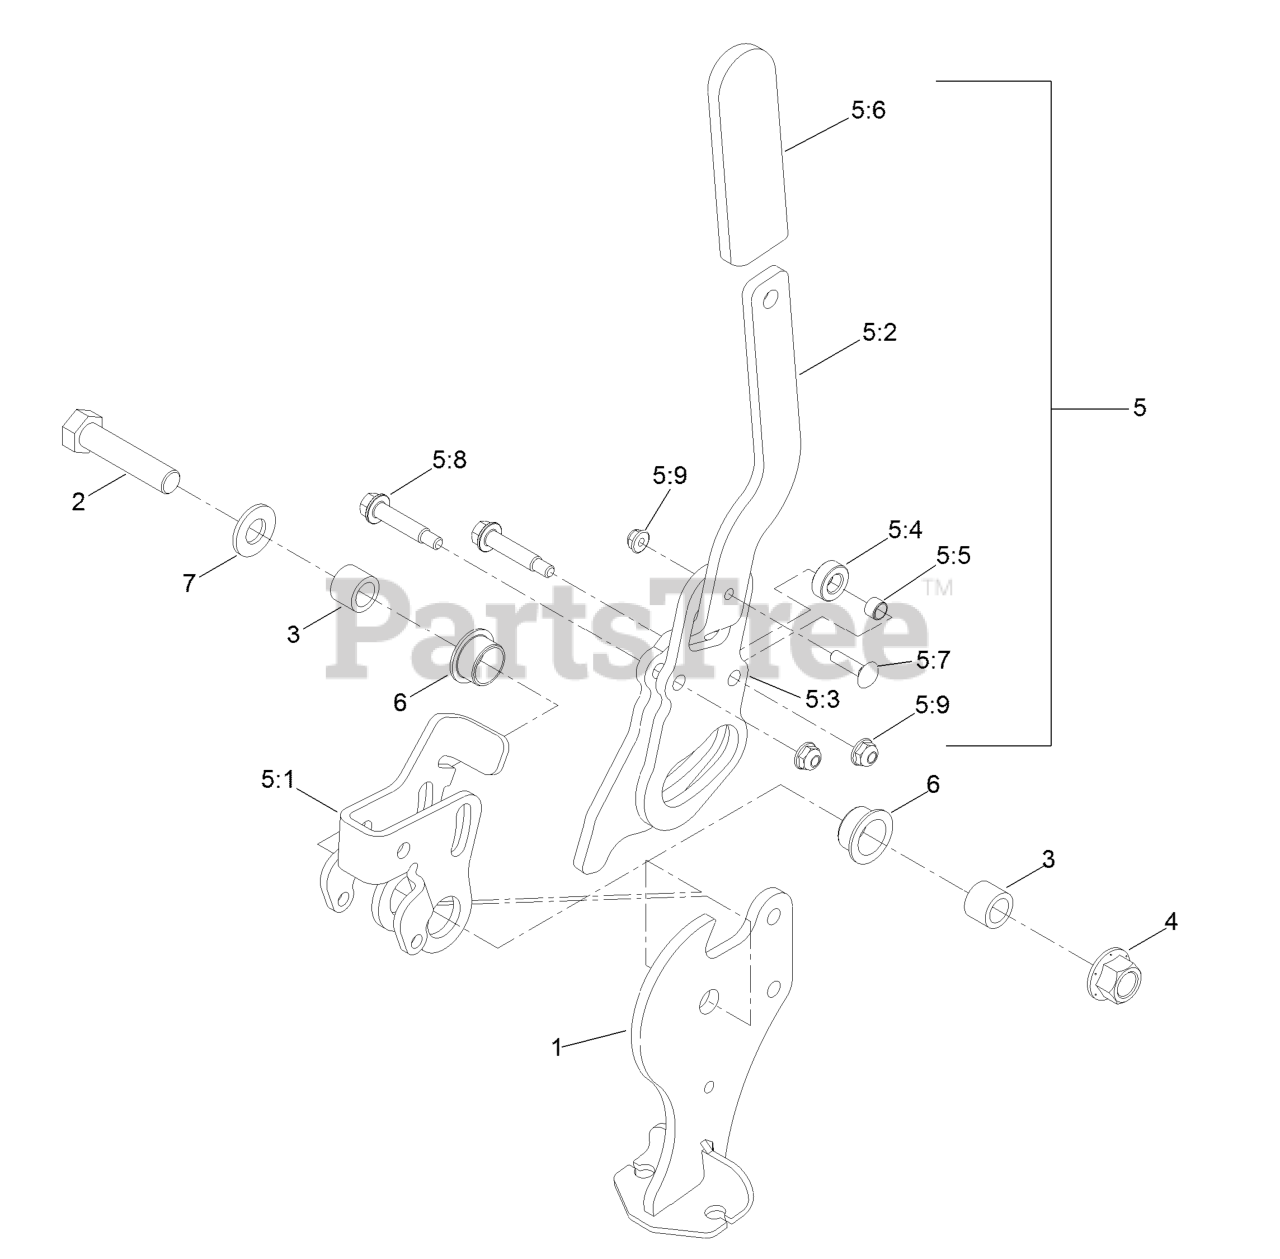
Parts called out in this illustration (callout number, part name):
1	PIVOT-BRAKE
2	SCREW-HH
4	Nut-Lock 1/2-13
5	HANDLE ASM
5:1	BELLCRANK-BRAKE
5:2	HANDLE-BRAKE
5:3	PLATE-HANDLE
5:4	ROLLER-BRAKE
5:5	BEARING-SLEEVE
5:6	GRIP-LEVER
5:7	SCREW-CARR
5:8	SCREW-SHOULDER
6	BUSHING-FLANGE
7	WASHER-FLAT
